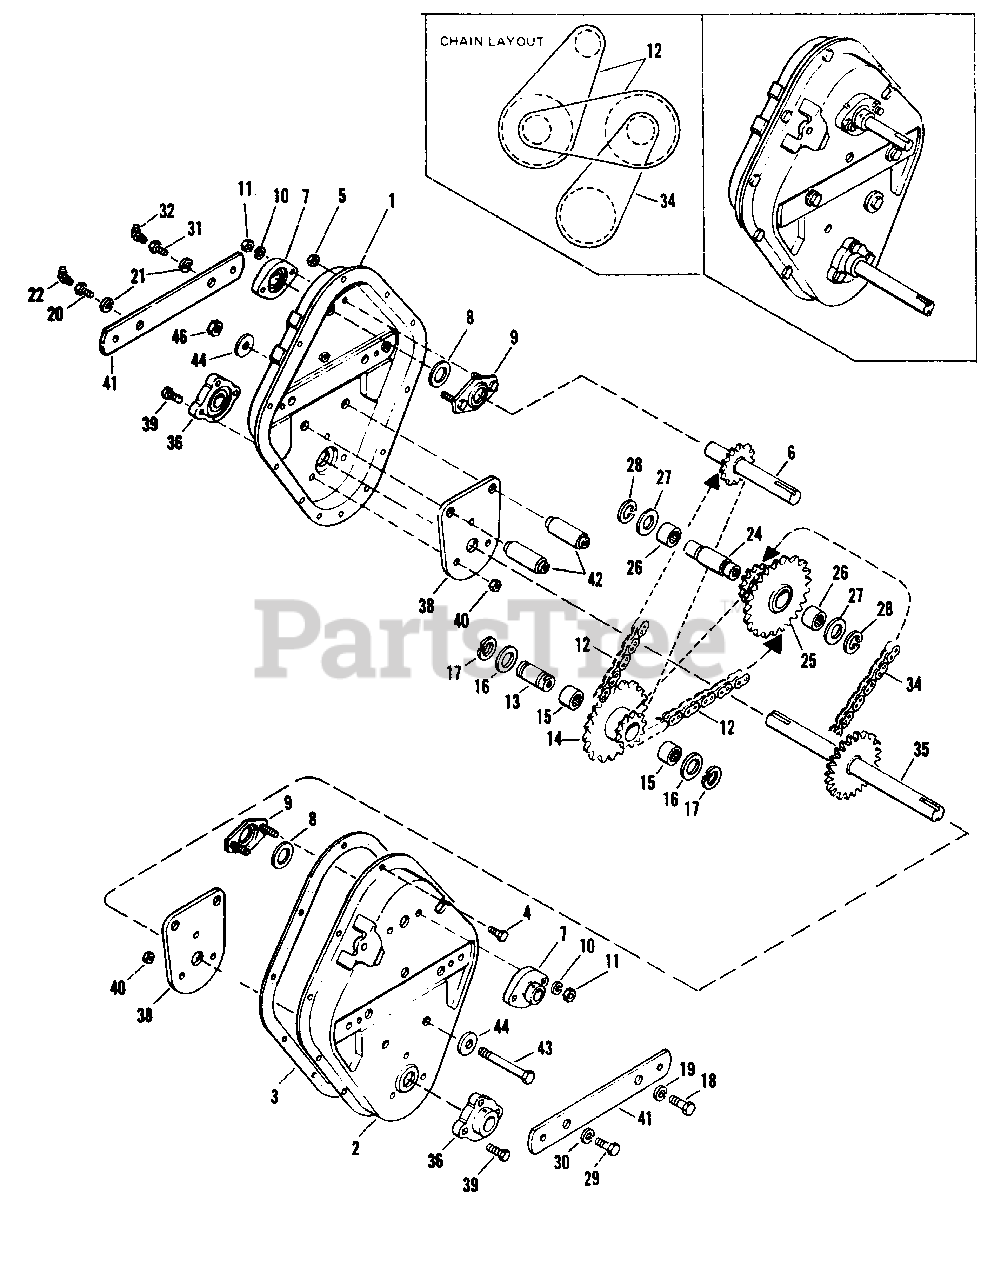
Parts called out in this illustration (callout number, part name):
1	Half Case Assembly, R.H.
2	Half Case Assembly, L.H.
4	Hex. Capscrew, 5/16"-18 x 5/8"
5	Full Hex. Locknut, 5/16"-18
6	Pulley Shaft Assembly
9	Upper Bearing Plate Assembly
10	Lock Washer, 5/16"
11	Full Hex. Nut, 5/16"-18
13	Inter. Spacer
14	Sprocket Assembly
15	Roller Bearing
17	Retaining Ring
18	Hex. Capscrew (L.H.Side), 1/2"-20 x 1-1/4"
19	Lock Washer, 1/2"
20	Bolt, (R.H. Side)
21	Lock Washer, 1/2"
22	Grease Fitting
24	Inter. Spacer
25	Sprocket Assembly
26	Roller Bearing
28	Retaining Ring
29	Hex. Capscrew (L.H. Side), 1/2"-20 x 1-1/4"
30	Lock Washer, 1/2"
31	Bolt (R.H. Side)
32	Grease Fitting
35	Tine Shaft Assembly
38	Reinf. Plate
39	Thread Forming Screw, 3/8"-16 x 1-1/2"
40	Hex. Jam Locknut, 3/8"-16
41	Side Bar, 3/16" x 2" x 13-1/16"
42	Spacer, 1" x 7/32" x 3-1/32"
43	Hex. Capscrew, 1/2"-13 x 4"
44	Plain Washer, 1/2"
46	Flange Locknut, 1/2-13
